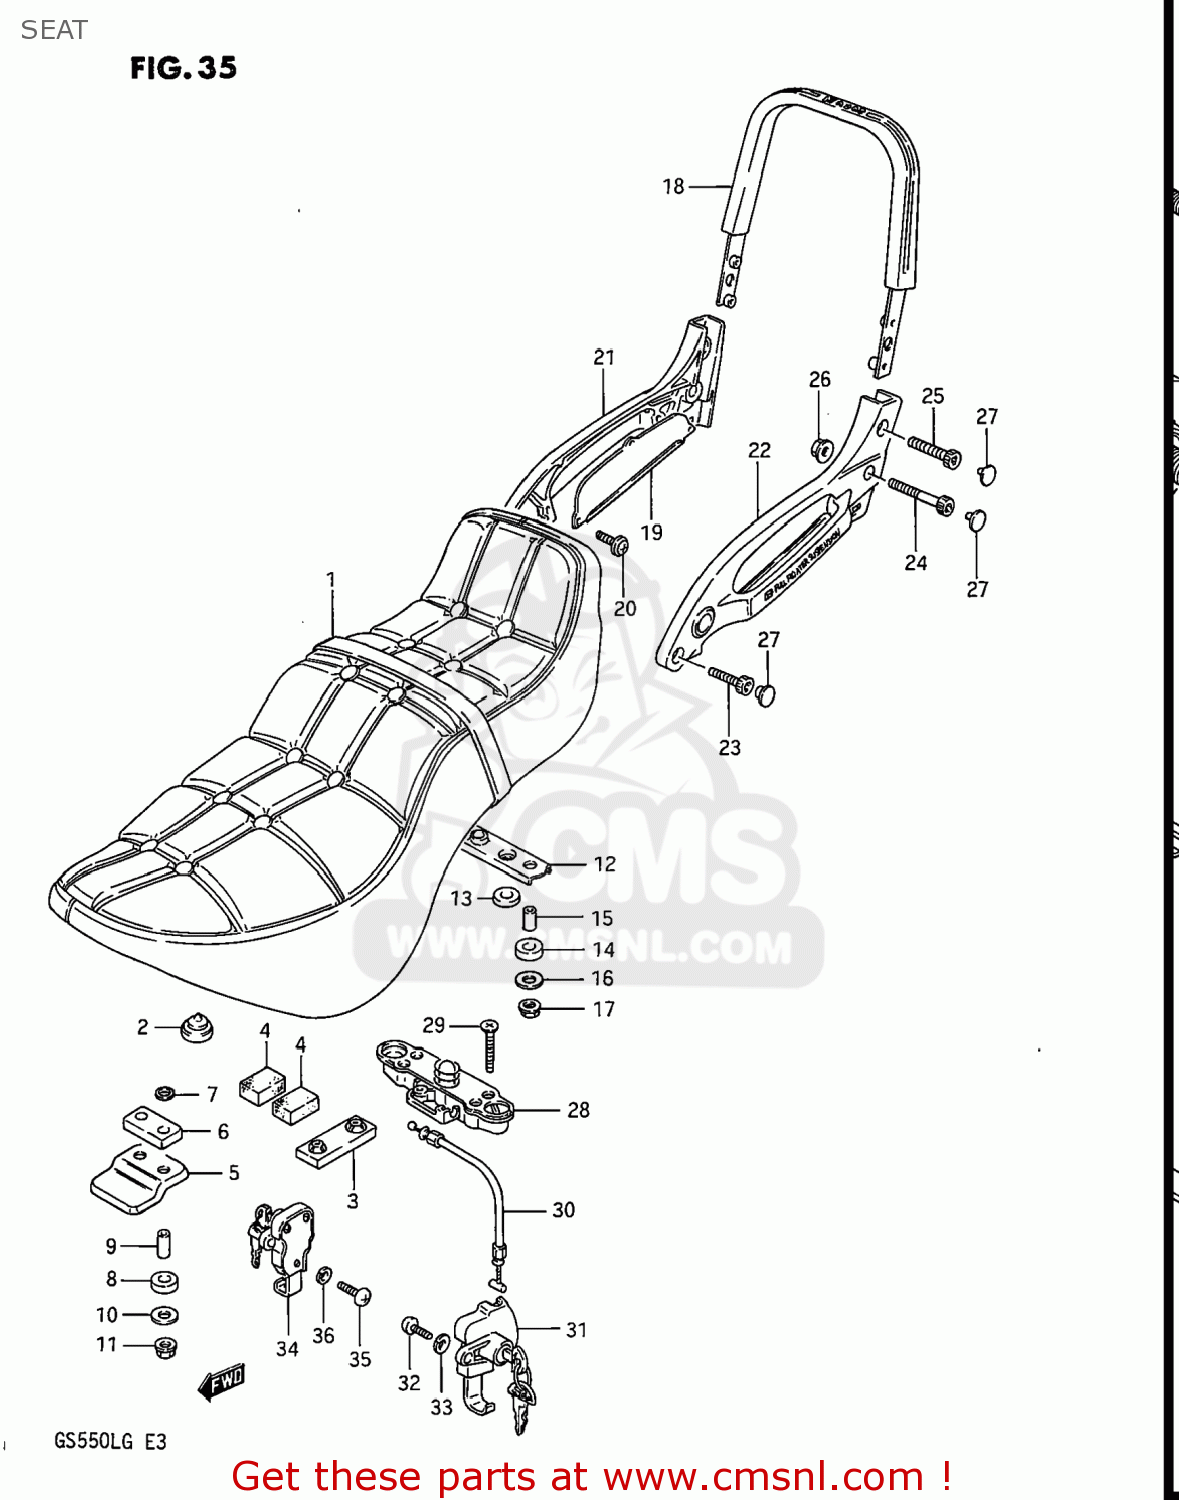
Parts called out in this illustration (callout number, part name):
1	SEAT ASSEMBLY
2	CUSHION
3	CUSHION,SEAT
4	CUSHION,BATTERY
5	PLATE,SEAT HOOK,FRONT
6	CUSHION,SEAT
7	WASHER
8	CUSHION
9	SPACER (6.1X8X12)
10	WASHER
11	NUT
12	STRIKER, SEAT LOCK
13	CUSHION,STRIKER
14	CUSHION,SEAT FR
15	SPACER (6.1X8X12)
16	WASHER
17	NUT
18	HANDLE,PILLION RIDER
20	SCREW
21	BRACKET,PILLION RIDER
22	BRACKET,PILLION RIDER
23	BOLT
24	BOLT
25	BOLT
26	NUT
27	CAP(OD:10)
28	LOCK ASSY,SEAT STRIKER
29	SCREW
30	CABLE,SEAT LOCK
31	LOCK ASSEMBLY,SEAT & HELMET
32	SCREW 6X12
33	WASHER,LOCK
34	LOCK ASSEMBLY,HELMET
35	SCREW 6X12
36	WASHER,LOCK
